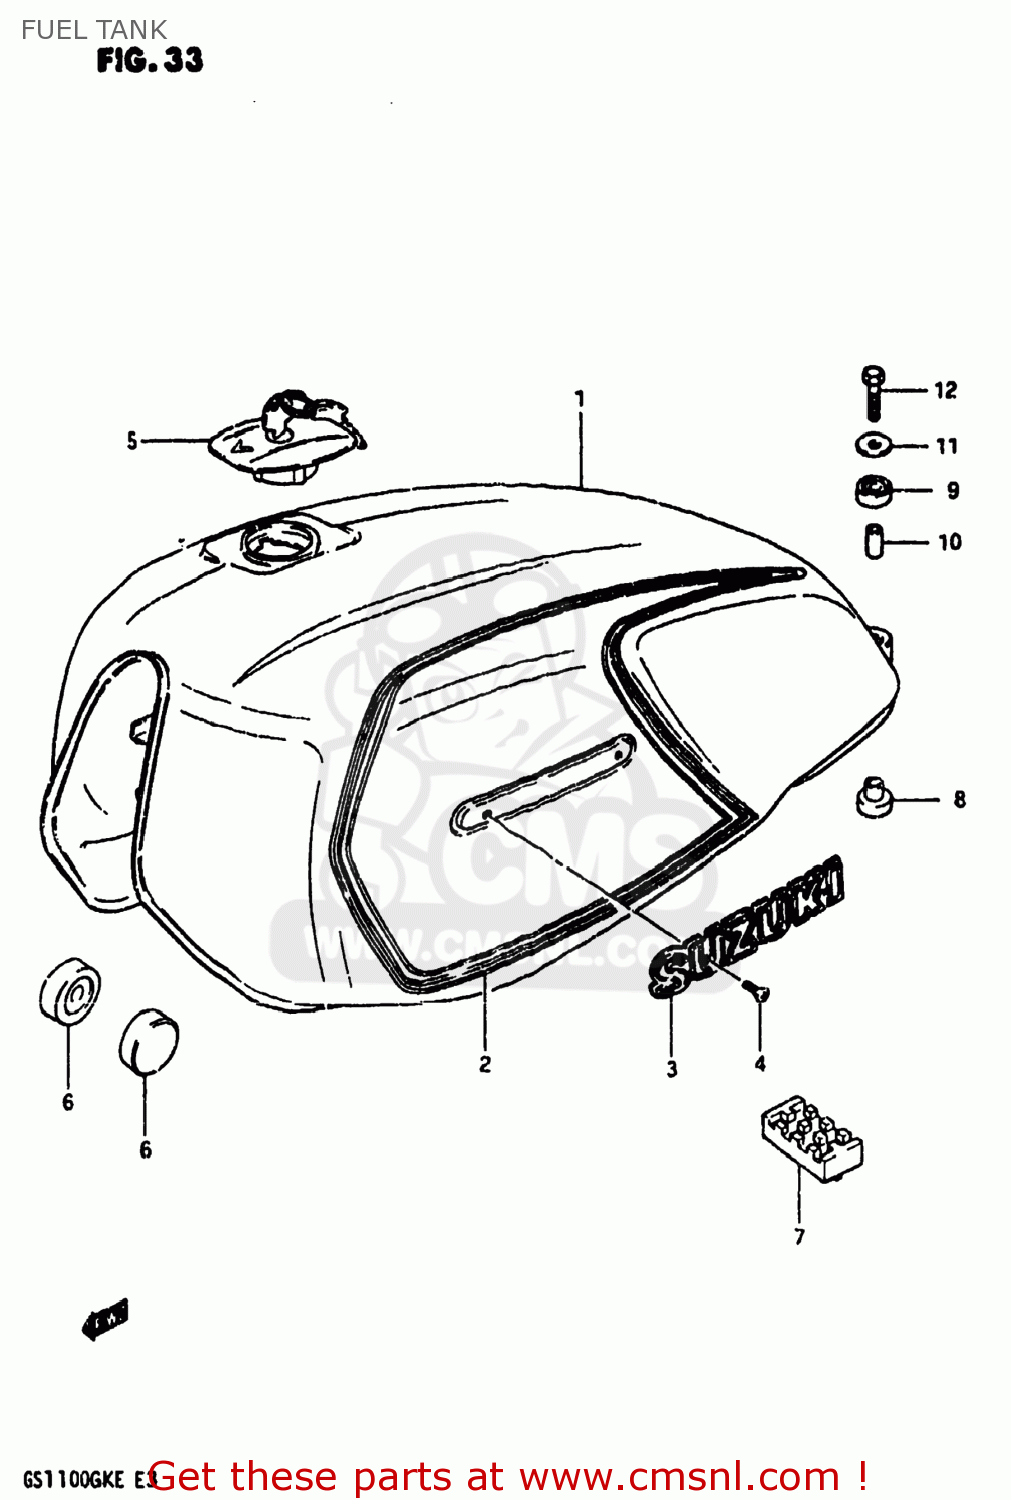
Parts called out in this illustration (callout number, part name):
1	TANK ASSEMBLY,FUEL
2	TAPE SET,FUEL TANK
3	EMBLEM
4	SCREW 3X6
5	CAP SET,FUEL TANK
6	CUSHION
7	CUSHION,FUEL TANK
8	CUSHION
9	CUSHION
10	SPACER (6.4X9X21.5)
11	WASHER (6.5X24X1.6)
12	BOLT
